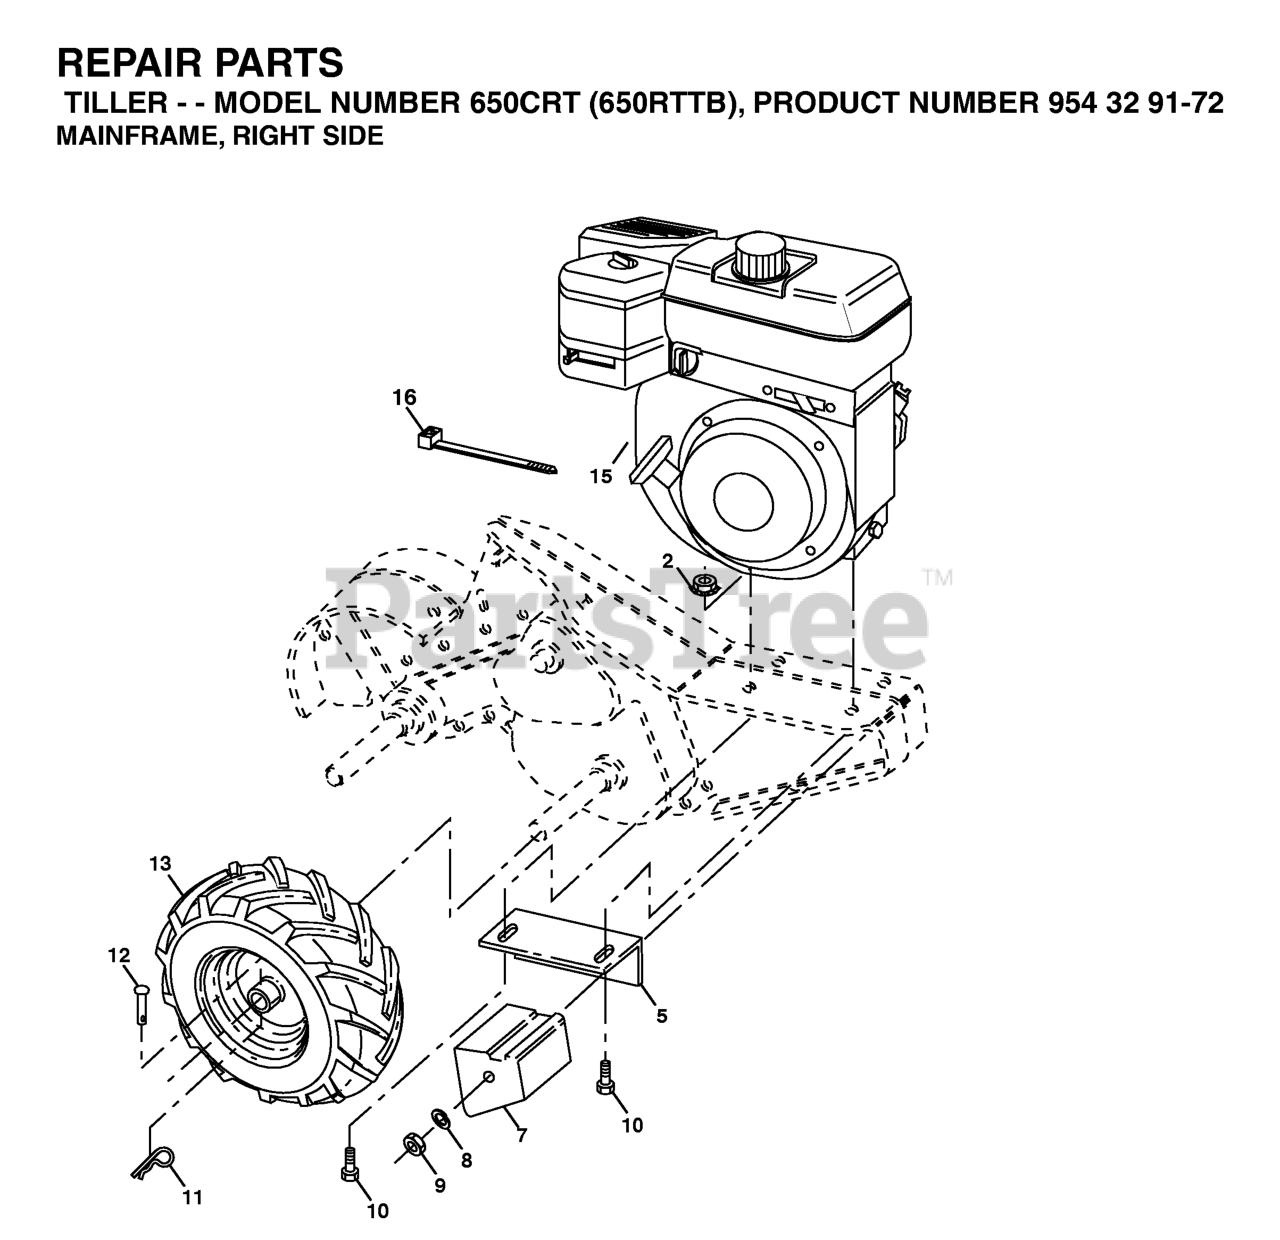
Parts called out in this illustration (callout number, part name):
2	LOCKNUT-FLANGE 5/16-18
5	DNO BRACKET RH CRT
7	COUNTERWEIGHT, RH
8	WASHER, LOCK 3/8
9	NUT.HEX.3/8-16UNC
10	BOLT
11	RETAINER M
12	RIVET,DRILLED
13	TIRE.16X4-8.CHEVRON.TILLER
16	TIE GUIDE
